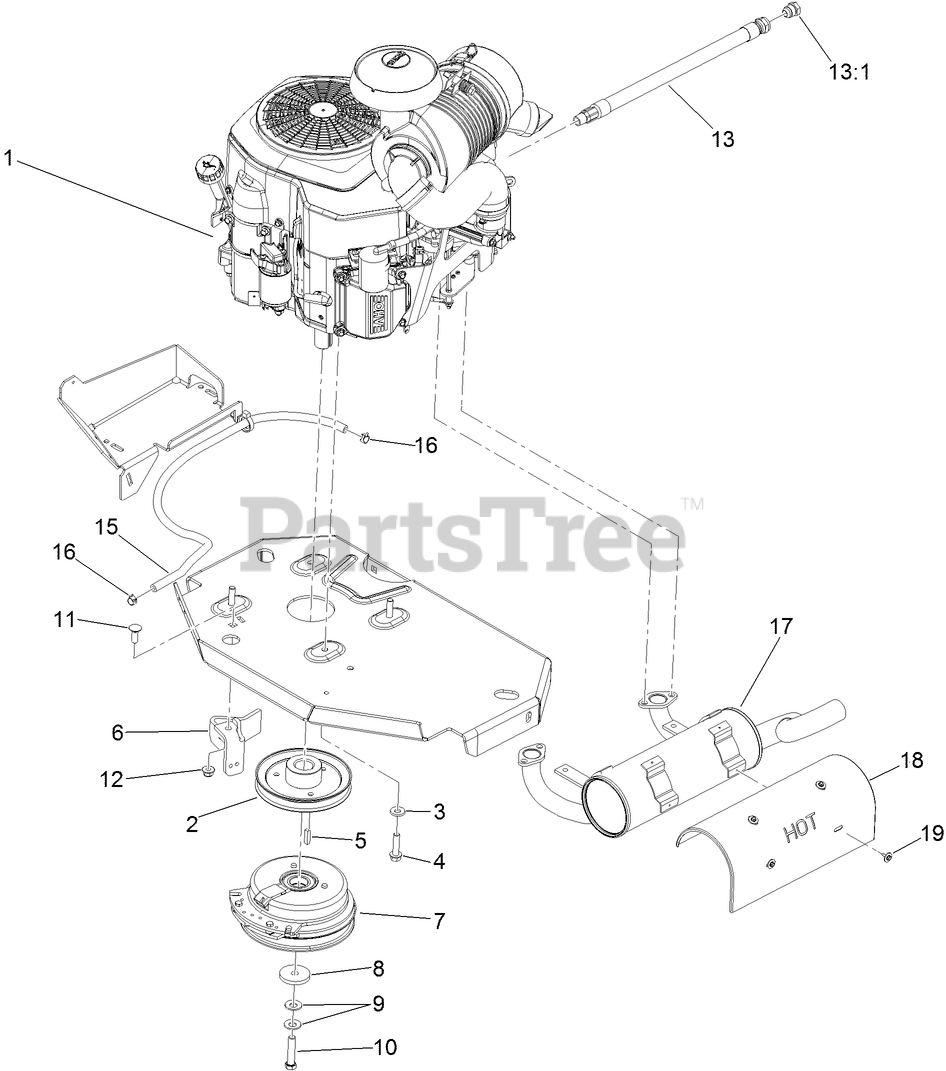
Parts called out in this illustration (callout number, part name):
2	SHEAVE
3	WASHER-BELLEVILLE
4	SCREW-HWH
6	CLUTCH-ANCHOR
7	CLUTCH KIT
8	WASHER-CLUTCH
9	WASHER-SPRING
10	SCREW-HH W/LOCTITE
11	SCREW-CARR
12	NUT-HF, NI
13	OIL DRAIN HOSE ASM
15	HOSE-FUEL
16	CLAMP-HOSE
17	MUFFLER
18	GUARD-MUFFLER
19	SCREW-HH, THREAD FORMING
